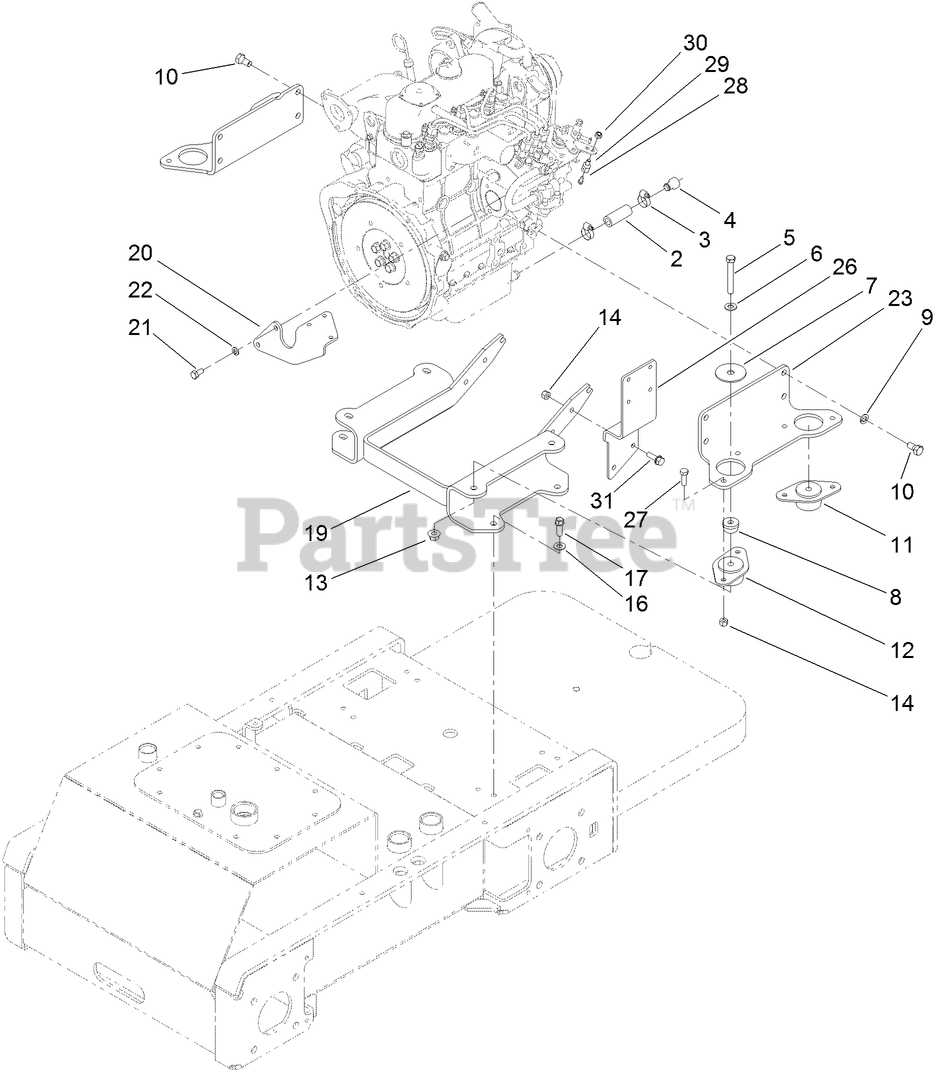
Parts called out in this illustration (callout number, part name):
2	HOSE-FUEL
3	CLAMP-HOSE
4	PLUG-OIL
5	SCREW-HH
6	WASHER-FLAT
7	WASHER-SNUBBING
8	SNUBBER-ENGINE MOUNT
9	WASHER-LOCK, SPRING
11	MOUNT-ENGINE
12	MOUNT-ENGINE
13	NUT-LOCK, FLANGE
14	NUT-LOCK, NI
16	WASHER-PLAIN
17	SCREW-TAPTITE
19	MOUNT-ENGINE
20	MOUNT-SOLENOID
21	BOLT
22	WASHER-LOCK
23	PLATE-MOUNT, ENGINE
26	MOUNT-FILTER, FUEL
27	SCREW-HH
28	SCREW-HH
29	SWIVEL-CABLE, THROTTLE
30	NUT-LOCK, NI
31	SCREW-HHF
